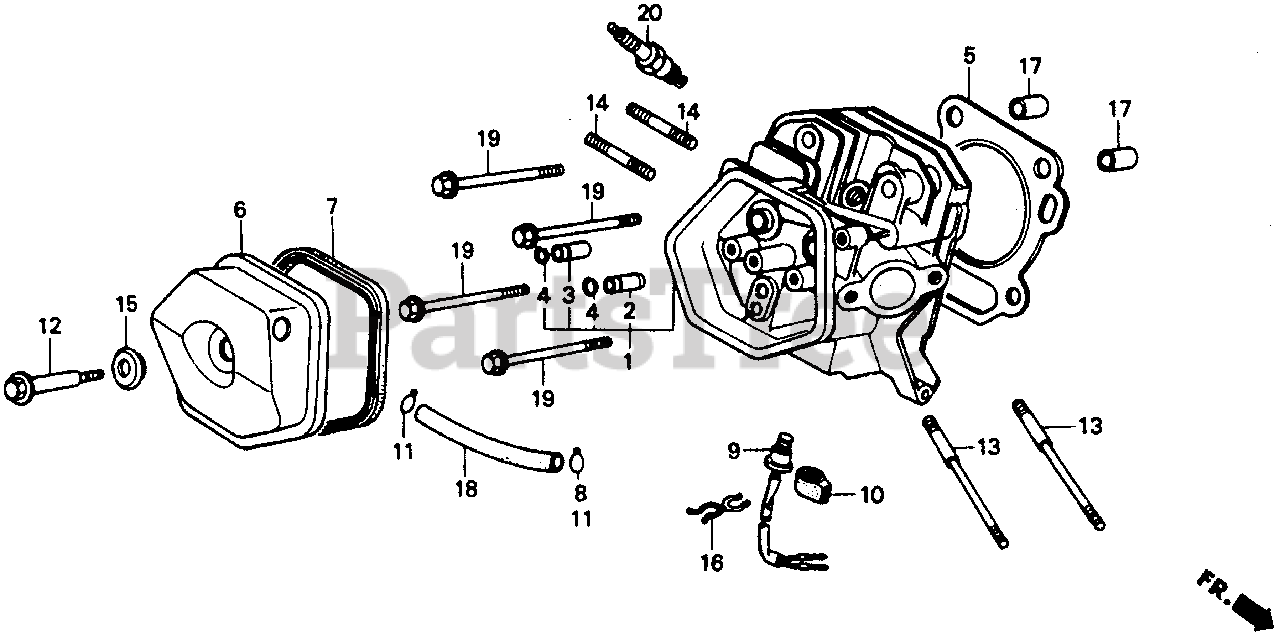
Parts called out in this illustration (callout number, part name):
1	CYLINDER HEAD
2	GUIDE, VALVE (OS)
3	GUIDE, EX. VALVE (OS)
4	CLIP, VALVE GUIDE
5	GASKET, CYLINDER HEAD
6	COVER KIT, HEAD
7	GASKET, CYLINDER HEAD COVER
12	BOLT, HEAD COVER
13	BOLT, STUD (8X131.5)
14	BOLT, STUD
14	BOLT 2, STUD (8X32)
15	WASHER, HEAD COVER
17	PIN A, DOWEL (12X20)
18	BULK HOSE, VACUUM (11X1000) (11X105)
19	BOLT, FLANGE (10X80)
20	SPARK PLUG (BPR5ES-11) (NGK)
20	SPARK PLUG (W16EPR-U11) (DENSO)
20	SPARK PLUG (BPR6ES-11) (NGK)
20	SPARK PLUG (W20EPR-U11) (DENSO)
